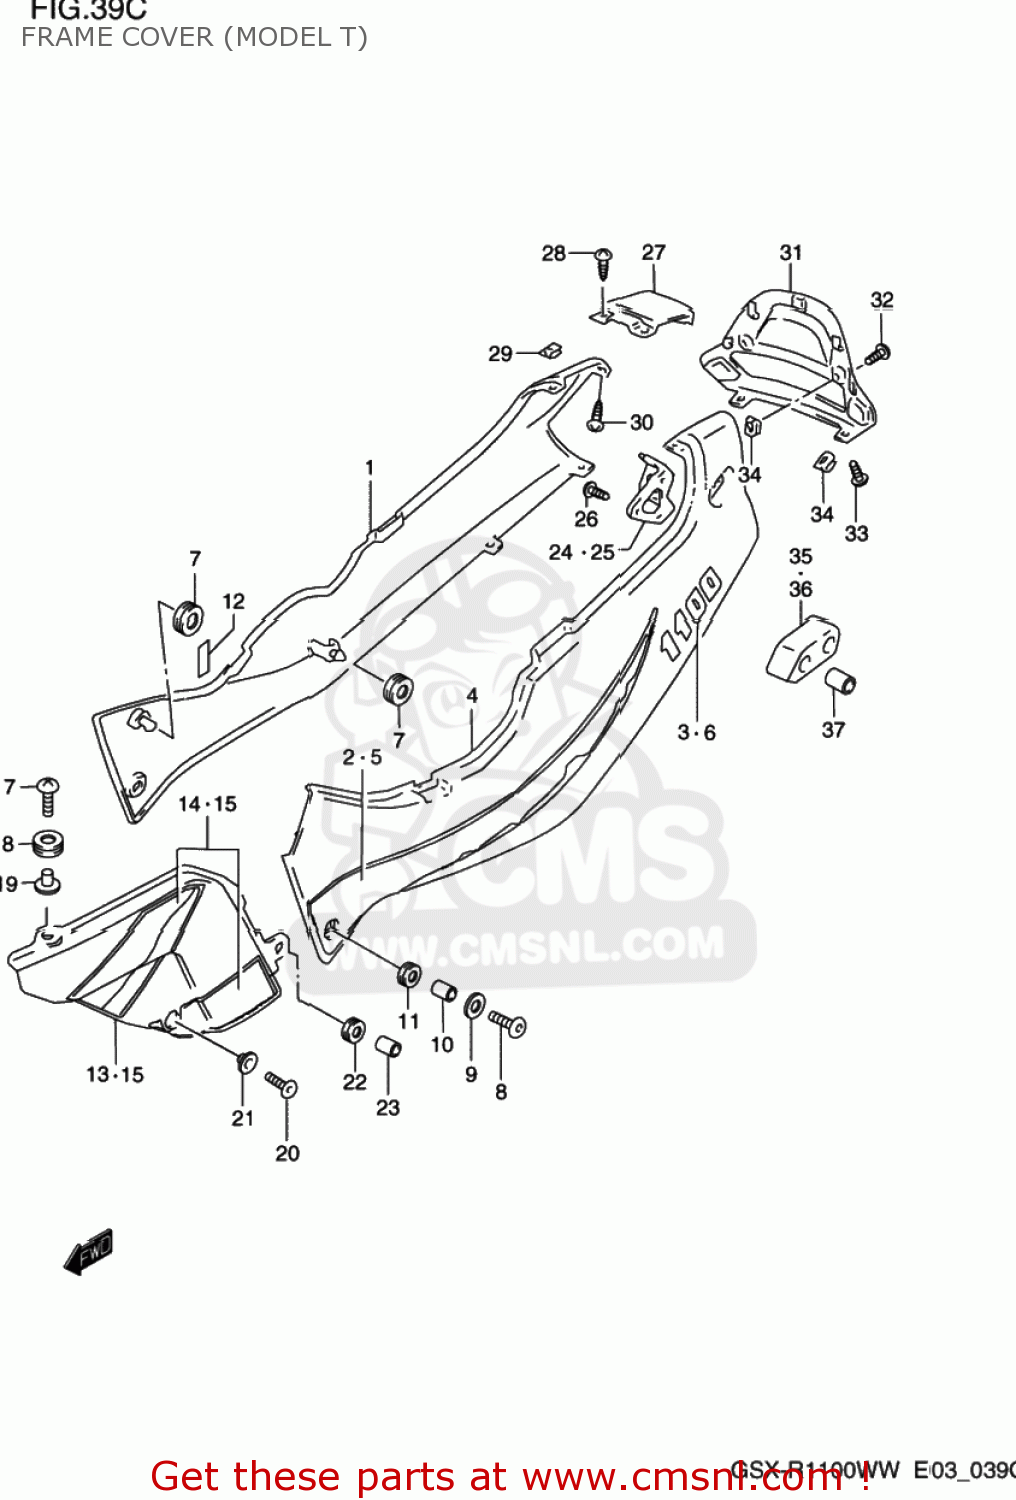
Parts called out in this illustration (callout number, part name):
1	COVER ASSY,FRAME,R(GRAY)
2	TAPE,FRAME COVER STRIPE
3	EMBLEM,FRAME COVER,R
4	COVER ASSY,FRAME,L(WHITE)
5	TAPE, FRONT LH
6	EMBLEM,FRAME COVER,L
7	CUSHION
8	SCREW(6X30)
9	WASHER
10	SPACER (6.1X9X9)
11	CUSHION
12	CUSHION
13	COVER ASSY,FRAME BODY,R
14	TAPE SET,FRAME COVER B
15	COVER ASSY,FRAME BODY,L
16	TAPE SET,FRAME COVER B
17	SCREW(6X25)
18	CUSHION
19	WASHER
20	SCREW(5X14)
21	WASHER
22	CUSHION
23	SPACER (6.1X9X9)
24	BRACKET,RR COMBINATION LAMP,L
25	BRACKET,RR COMBINATION LAMP,L
26	SCREW
27	COVER ASSY,FRAME CTR
28	SCREW 5X12
29	NUT
30	SCREW
31	COVER,FRAME RR
32	SCREW(5X12)
33	SCREW 5X12
34	NUT
35	CUSHION,PILLION RIDER HANDLE,R
36	CUSHION,PILLION RIDER HANDLE,L
37	SPACER (8.5X16X37)
